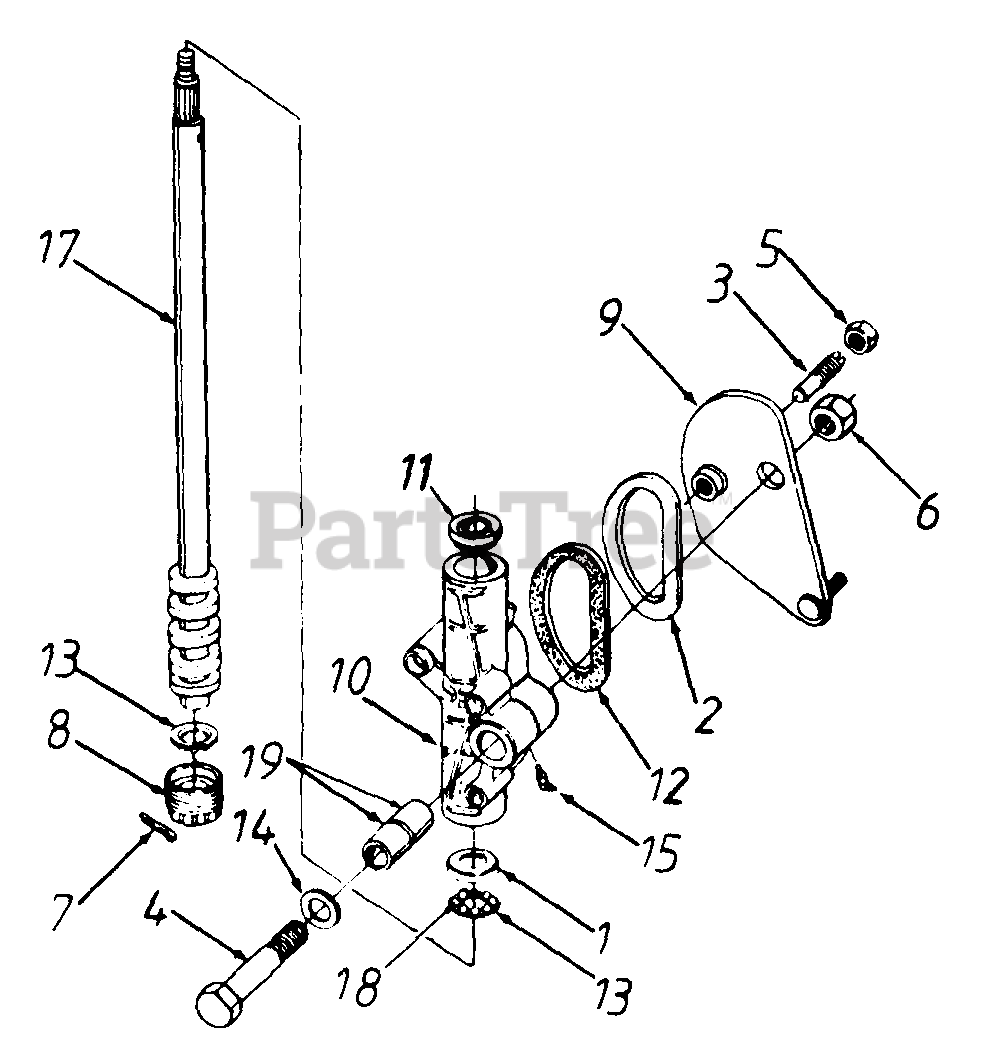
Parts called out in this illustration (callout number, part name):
1	Bearing Cup
2	Seal Retainer
3	Cam Follower
4	Pivot Shaft
5	Hex Jam Nut 9/16-18 Thd.
6	Hex Crown L-Nut 5/8-18 Thd.
7	Cotter Pin 1/8" Dia.
8	Adjustment Plug Ass'y.
9	Steering Arm Ass'y.
10	Steering Gear Hsg.
11	Oil Seal
12	Seal
13	Ball Retainer
14	Fl-Wash..781" I.D. x 1.25" O.D.
15	Grease Fitting
17	Steering Shaft Ass'y.
18	Ball Bearing
19	Housing Bushing
